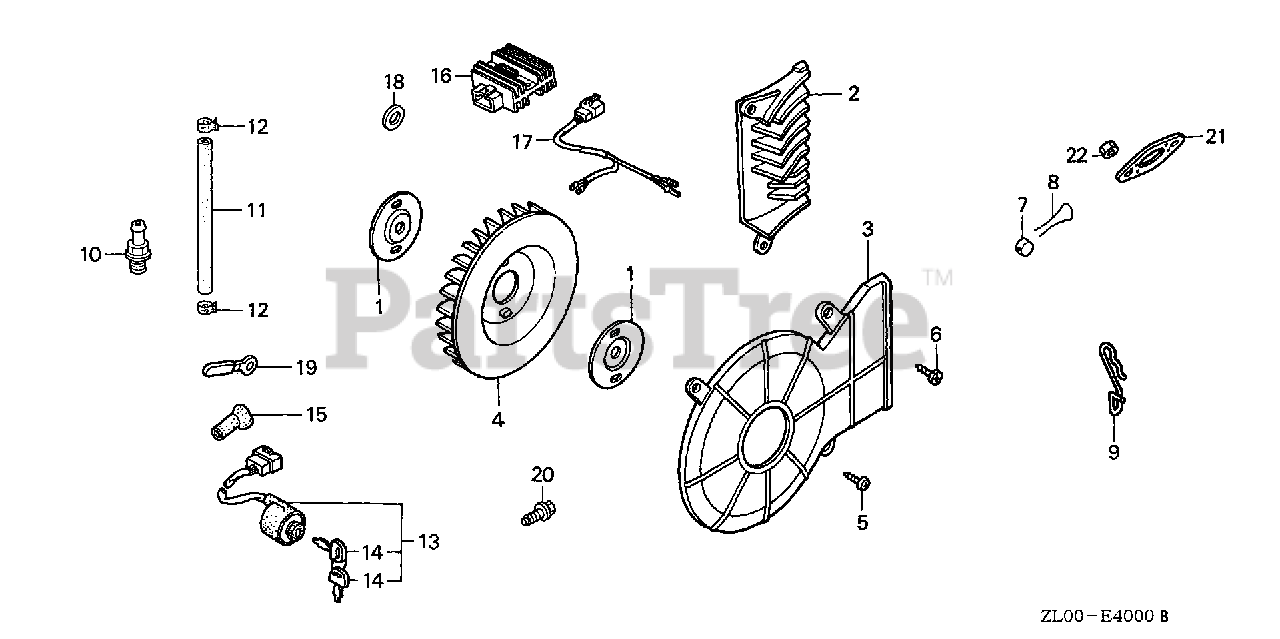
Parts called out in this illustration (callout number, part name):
10	JOINT, DRAIN
11	TUBE, DRAIN
12	CLAMP, TUBE (D12)
18	WASHER, DRAIN PLUG (10.2MM)
